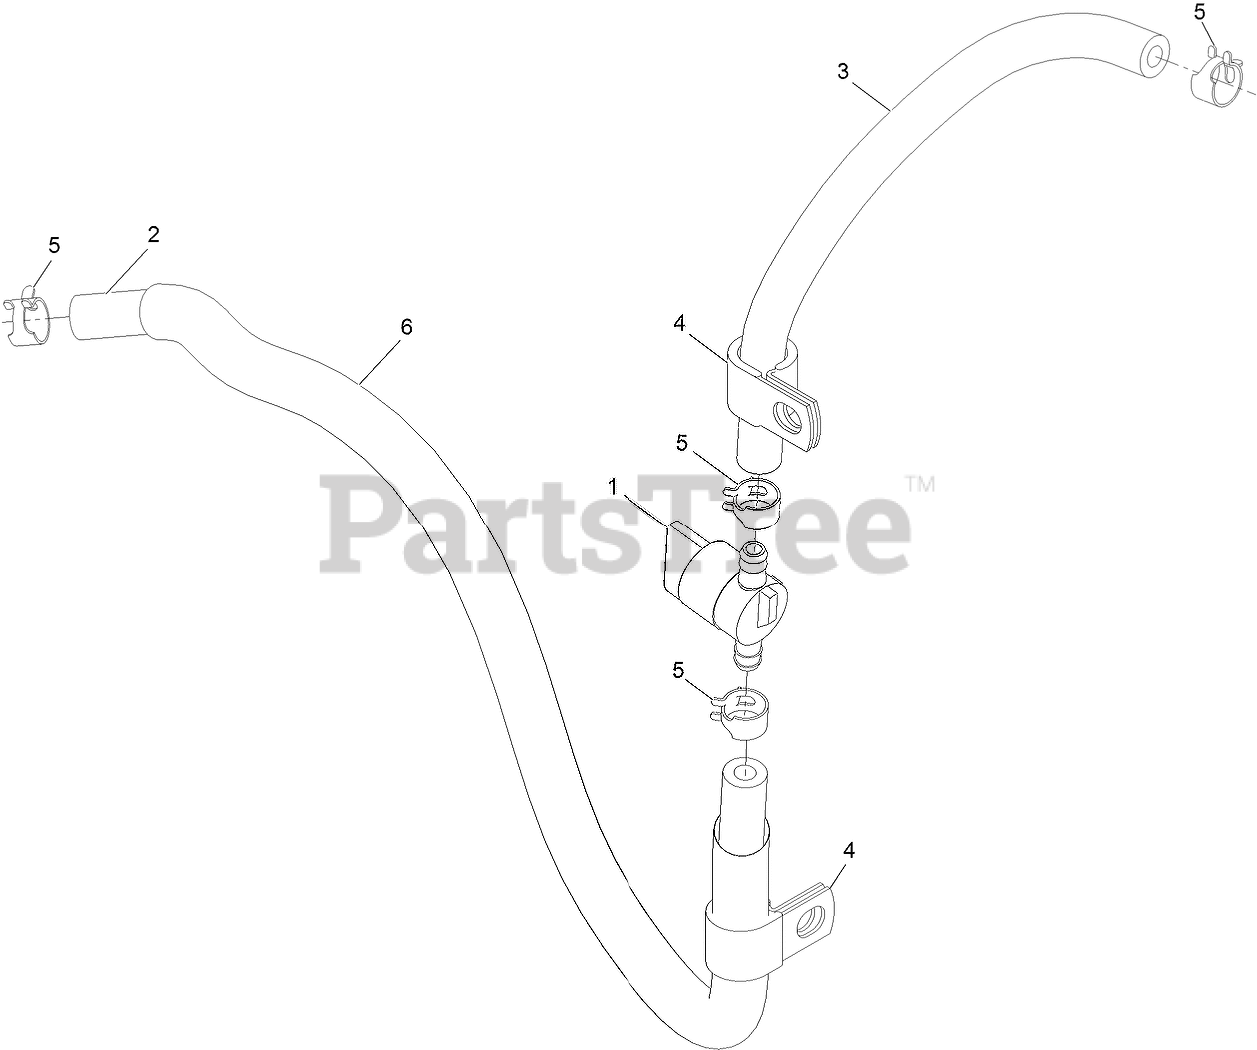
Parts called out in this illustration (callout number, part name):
1	VALVE-FUEL
2	HOSE-FUEL
3	HOSE-FUEL
4	CLAMP-R
5	CLAMP-HOSE
6	Sleeve-Thermal
